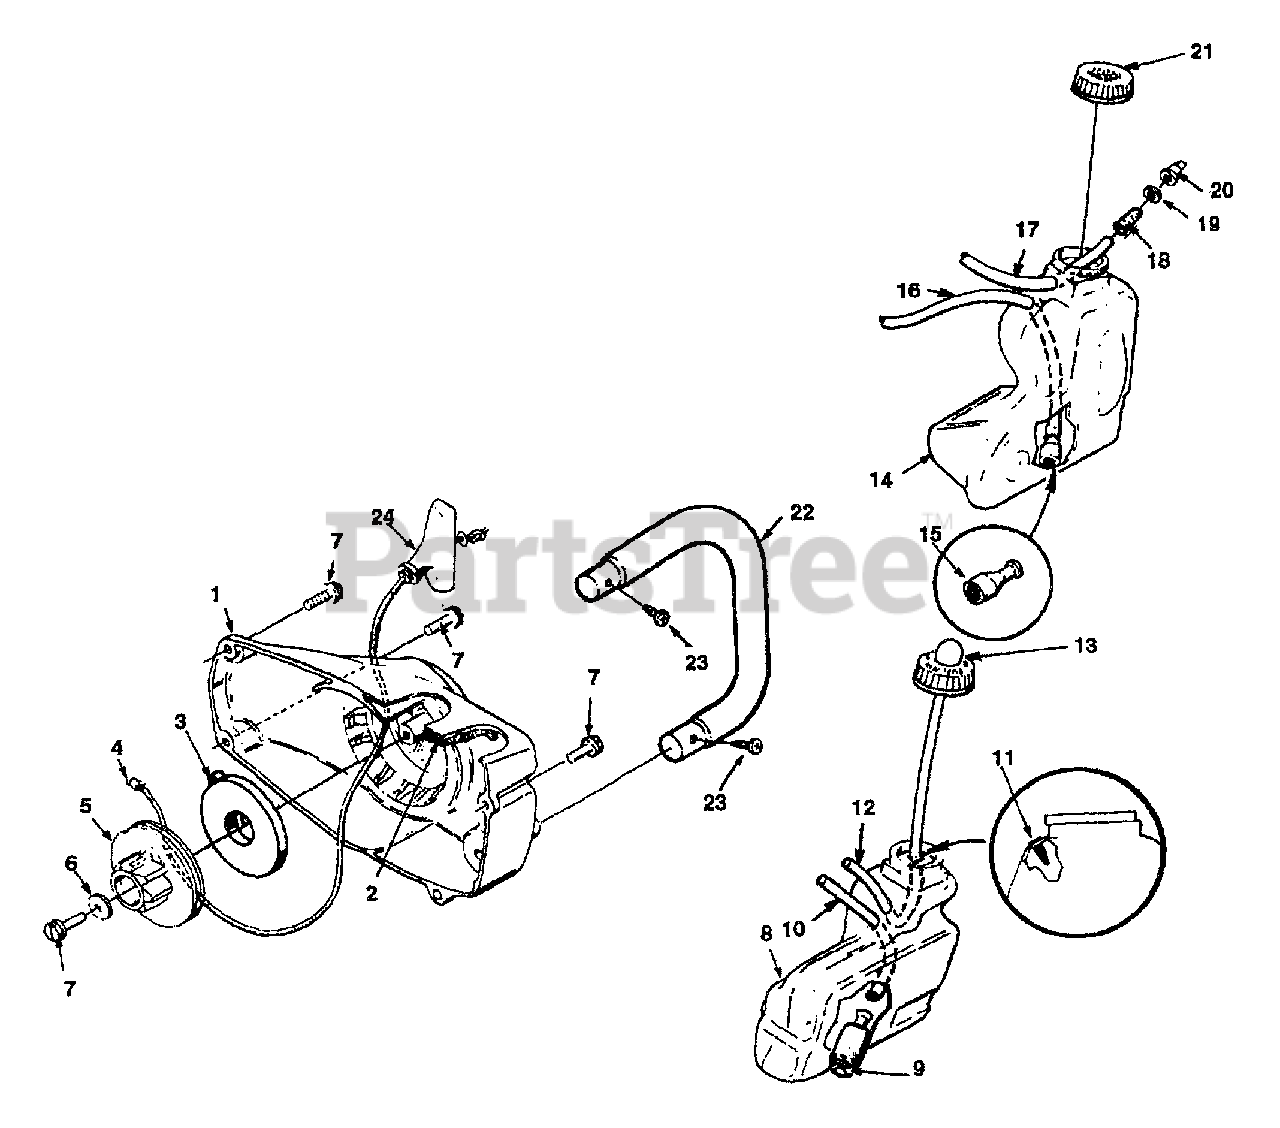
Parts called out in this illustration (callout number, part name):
1	STARTER HOUSING ASSY.
3	SPRING & CONTAINER
4	ROPE-Starter (46")
5	PULLEY Starter
6	WASHER-Retaining
7	SCREW-Torx (#10 x 3/4")
8	FUEL TANK
9	FILTER- Fuel
10	LINE-Fuel (5 1/2")
11	VALVE-Check
12	TUBING-Return 6 1/4"
13	PRIMER & CAP
14	OIL TANK
15	FINDER-Oil
16	TUBING-Rubber (8")
17	TUBING-Rubber (4 3/4")
18	FITTING-Oil
19	WASHER- Lock
20	VALVE-Check
22	HANDLE BAR
23	SCREW- Pan Plastite (#10-16 x 3/4")
24	GRIP-Starter
